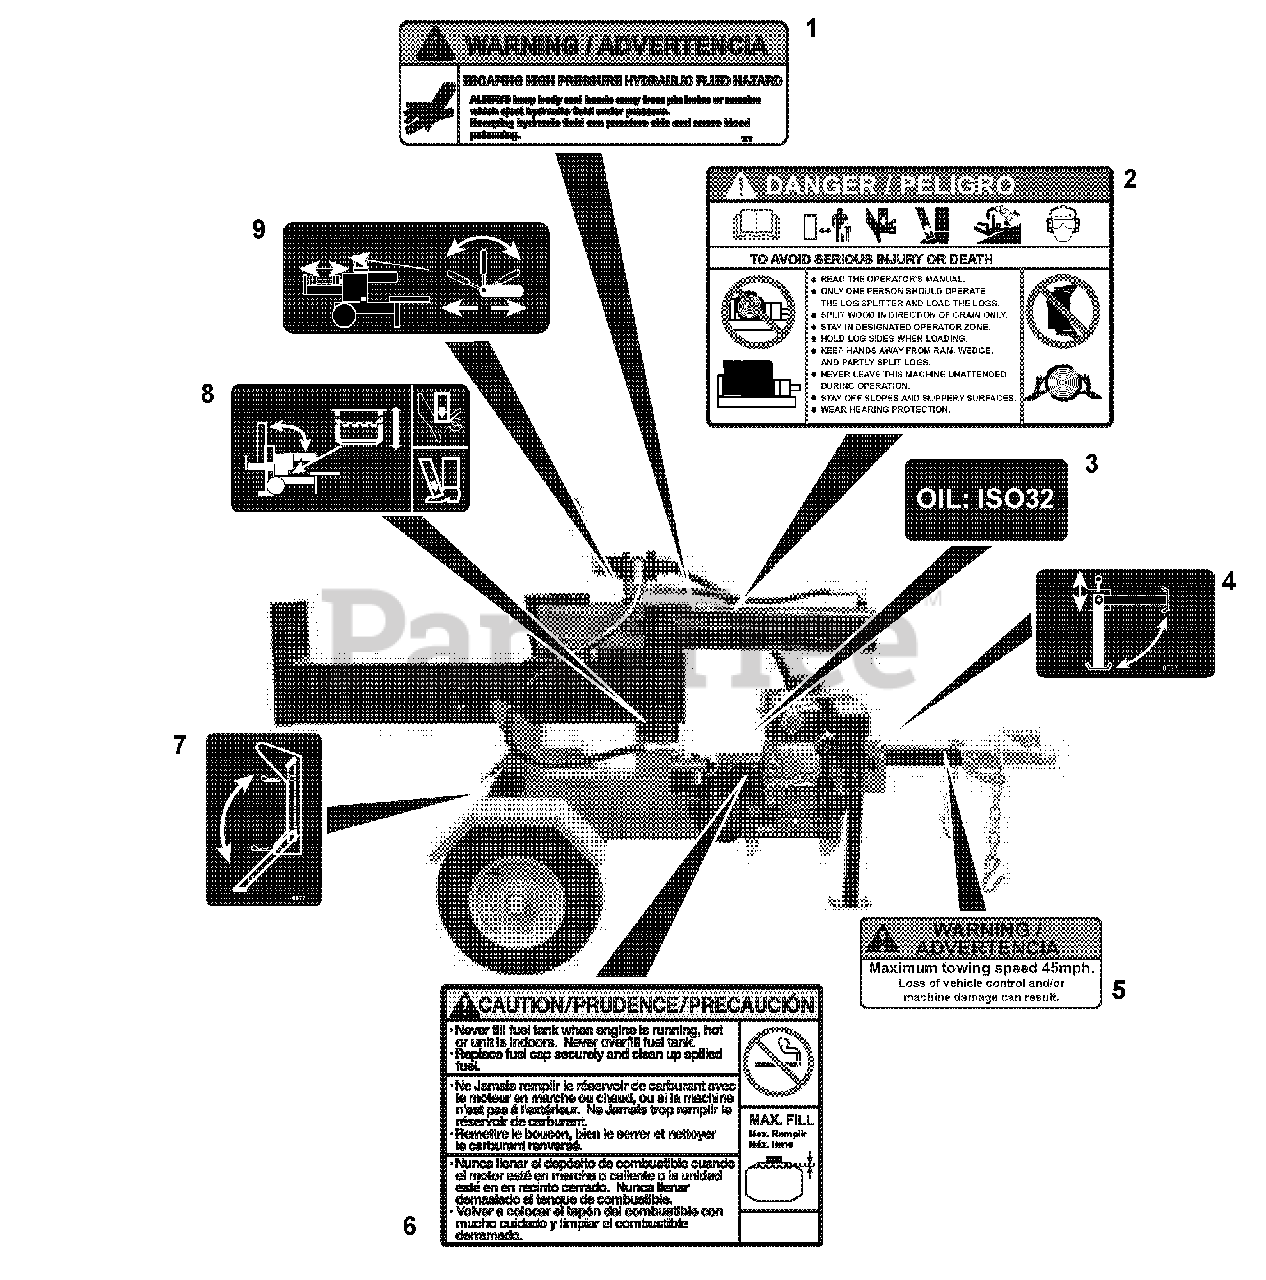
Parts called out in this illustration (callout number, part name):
1	DECAL,LOG SPLITTER-HYD WARNING
2	DECAL, LOG SPLITTER-DANGER
3	DECAL, LOG SPLITTER-HYD OIL
4	DECAL,LOG SPLITTER-FRONT STAND
5	DECAL, LOG SPLITTER-TOWING
6	DECAL,LOG SPLITTER-GAS CAUTION
7	DECAL, LOG SPLITTER-REAR STAND
8	DECAL, LOG SPLITTER-TILT OP
9	DECAL, LOG SPLITTER-RAM OP
10	DECAL SHEET,LOG SPLITTER
